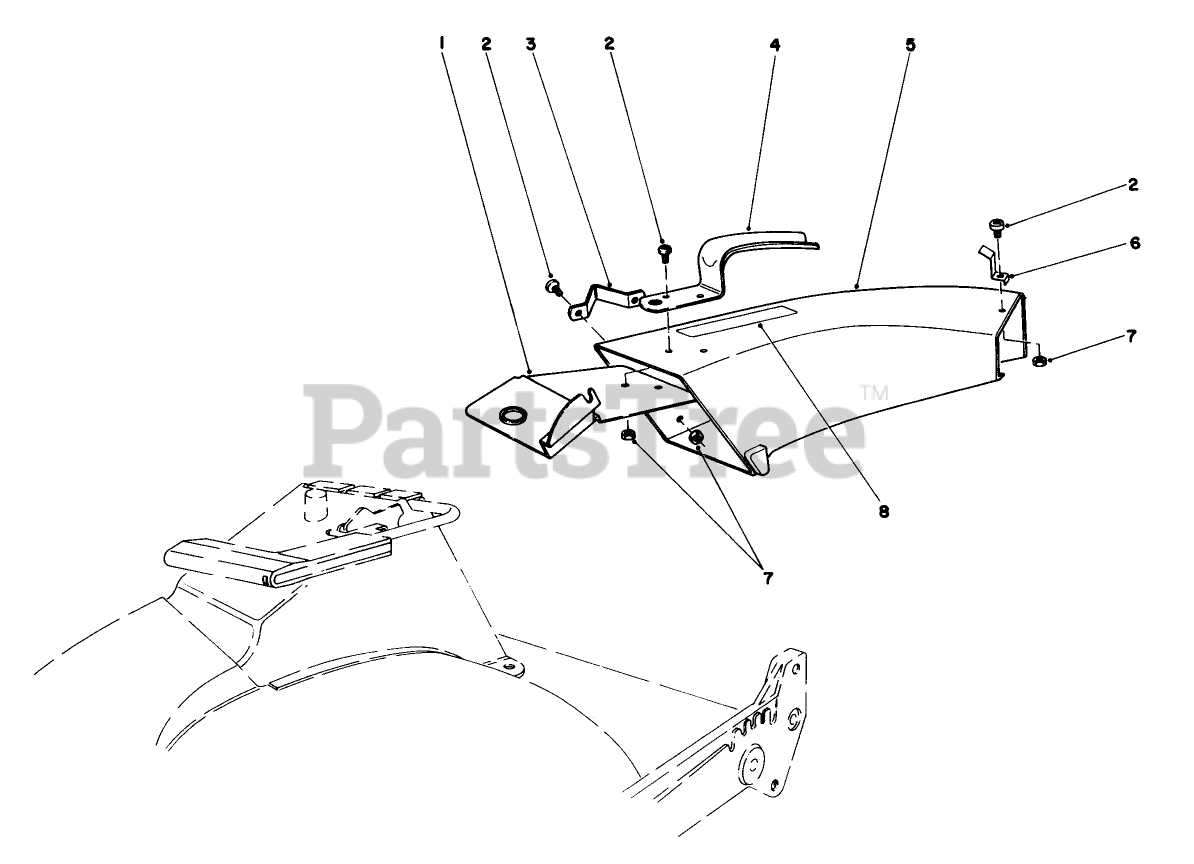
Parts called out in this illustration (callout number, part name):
2	10-24 X 5/8 PAN HD MS
4	CHUTE HANDLE
5	Chute-Discharge
7	NUT-LOCK, NI
